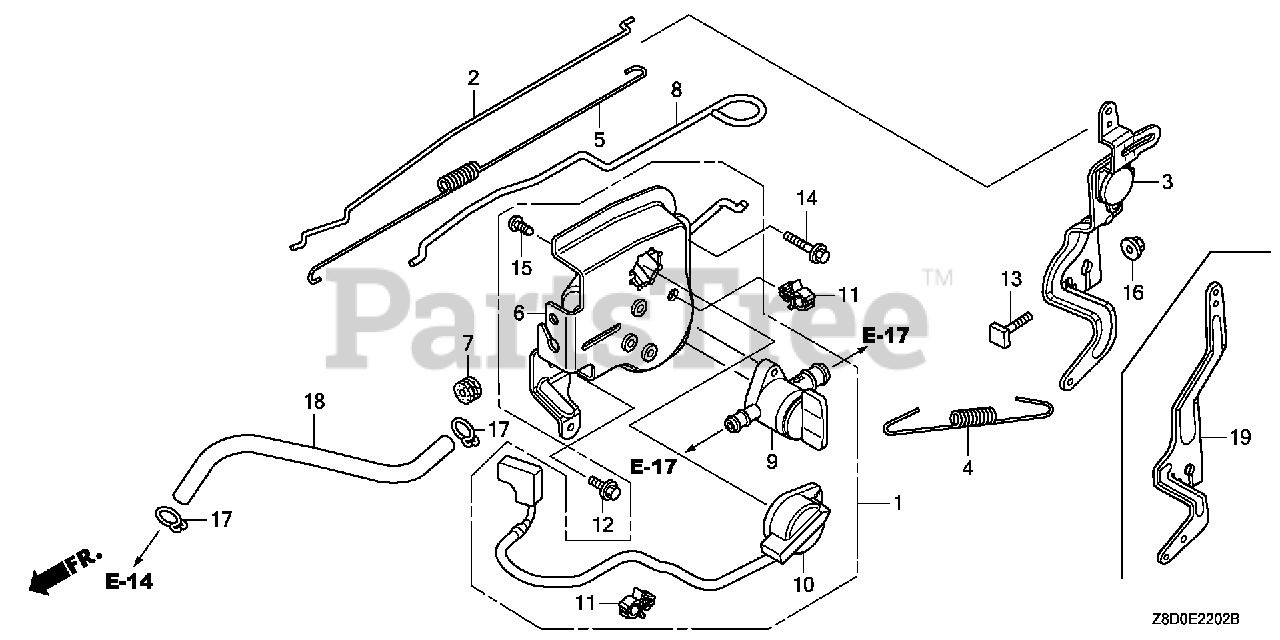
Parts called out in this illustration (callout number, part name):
2	ROD, GOVERNOR
4	SPRING, GOVERNOR
5	SPRING, THROTTLE RETURN
6	BASE, CONTROL
7	GROMMET, CHOKE ROD
8	ROD, CHOKE
9	PETCOCK ASSY.
10	SWITCH ASSY., ENGINE STOP
11	HOLDER, WIRE (FASTEX)
12	BOLT, FLANGE (6X14)
13	BOLT, GOVERNOR ARM
14	BOLT, FLANGE (6X32)
15	SCREW, TAPPING (5X12) (PO)
16	NUT, FLANGE (6MM)
19	ARM, GOVERNOR
